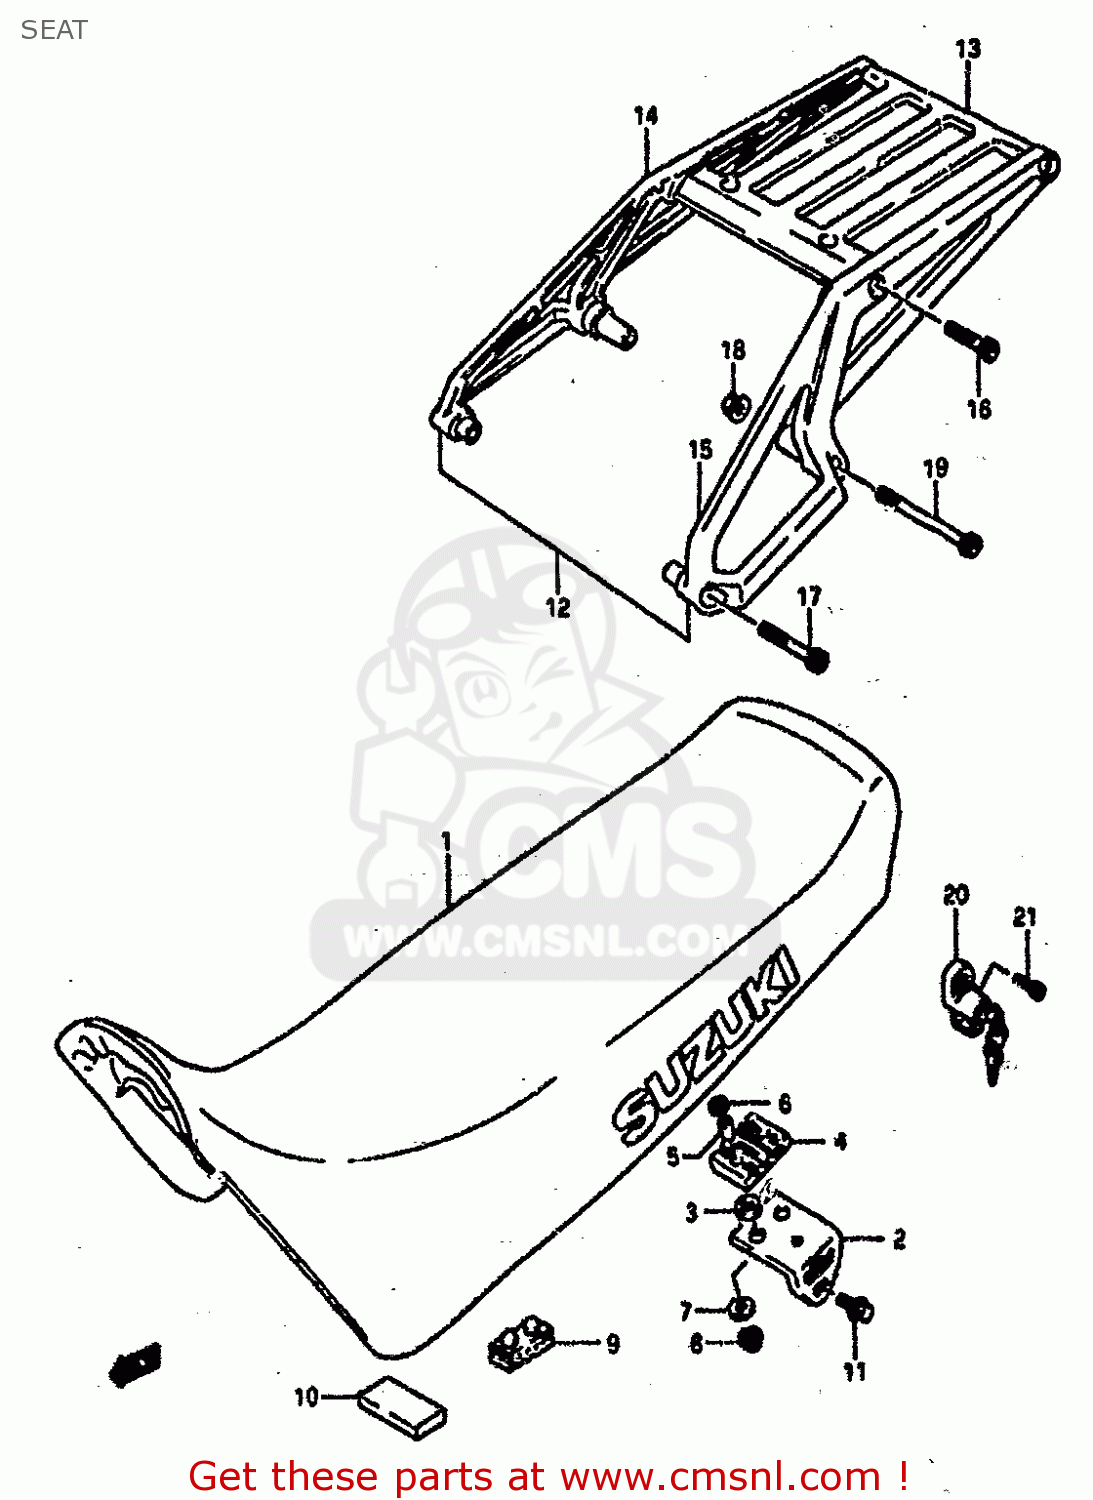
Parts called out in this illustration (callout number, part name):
1	SEAT SET
2	BRACKET,SEAT
3	CUSHION,SEAT FR
4	CUSHION,FR PLATE
5	SPACER,SEAT SUPPORT
6	WASHER
7	WASHER, LOWER
8	NUT
9	CUSHION,SEAT(40X20X15)
10	CUSHION(30X60X10)
11	BOLT
12	CARRIER,REAR (SILVER)
13	REAR CARRIER,CENTER (SILVER)
14	CARRIER,RR,R(SILVER)
15	REAR CARRIER,LH (SILVER)
16	BOLT
17	BOLT(8X50)
18	BOLT ,8X50
19	NUT
20	BOLT
21	LOCK SET,HELMET
22	BOLT
23	LABEL,ASBESTOS WARNING
